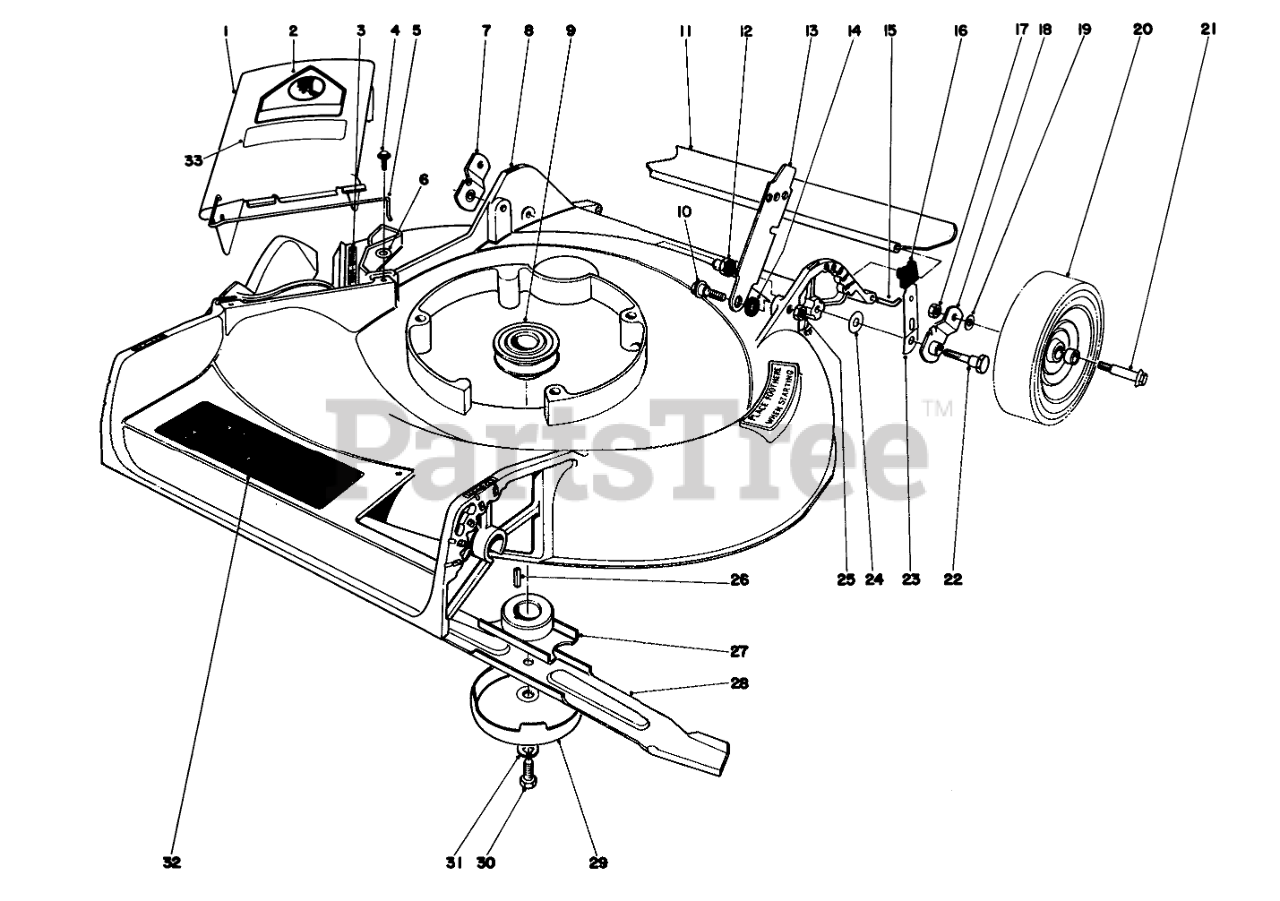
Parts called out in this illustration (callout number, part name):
1	Deflector Cover Assembly (Incl. Ref. #2, 5 & 33)
2	DECAL-DANGER
3	Decal
4	SCREW
5	SPRING HINGE
6	WASHER-FLAT
7	Pivot Arm
8	Housing (Incl. Ref. #3)
9	DRIVER PULLEY
10	SCREW-SHOULDER
11	REAR SAFETY SHIELD 21
12	HANDLE PIVOT NUT
13	Latch
14	HANDLE LATCH SPACER
15	SHIELD ROD
16	KNOB-ARM
17	Nut
18	Pivot Arm
19	WASHER
20	WHEEL TIRE ASM 8 IN
21	BOLT-WHEEL
22	5/16-18 PIVOT SCREW
23	SPRING ARM ASM
24	WASHER-PIVOT
25	Nut
26	KEY-SQUARE
27	Blade Retailer
28	Blade
29	AntiScalp Cup
30	SPECIAL SCREW
31	WASHER-LOCK
32	Decal-Side Discharge
33	DECAL DEFLECTOR
